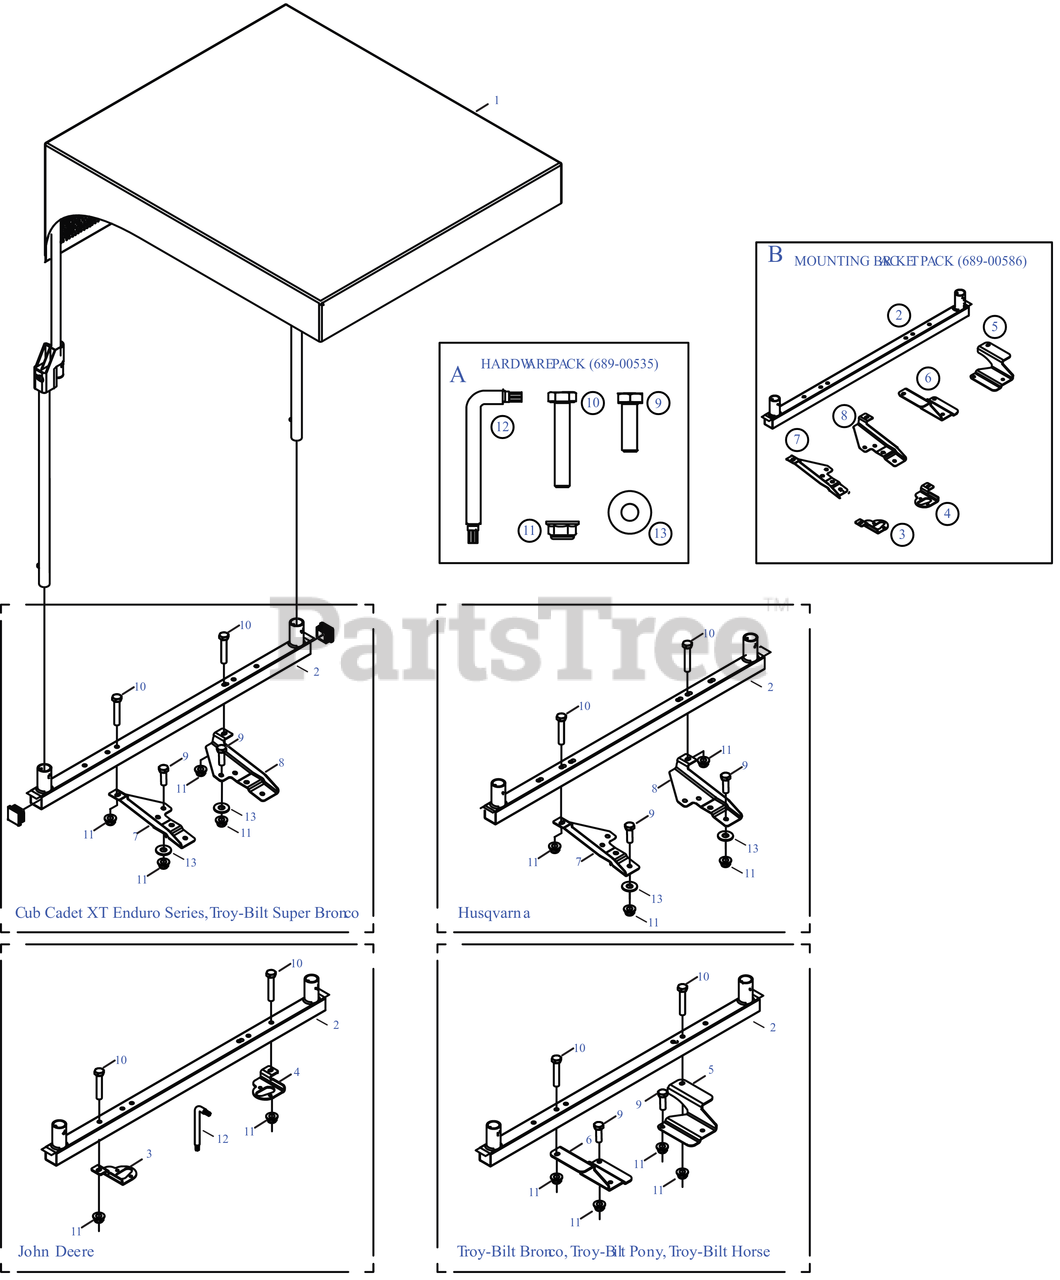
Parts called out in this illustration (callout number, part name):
1	UNIVERSAL SUNSHADE CANOPY
2	Support
3	Mounting Bracket (RH)
4	Mounting Bracket (LH)
5	Mounting Bracket (LH)
6	Mounting Bracket (RH)
7	Mounting Bracket (RH)
8	Mounting Bracket (LH)
9	SCREW 5/16-18 x 1.0 GR5
10	SCREW 5/16-18 x 1.75 GR5
11	FLANGE LOCK NUT 5/16-18
12	TORX DRIVER T30
13	FLAT WASHER
B	MOUNTING BRACKETS (UNIVERSAL SUNSHADE)
A	HARDWARE PACK (UNIVERSAL SUNSHADE)
